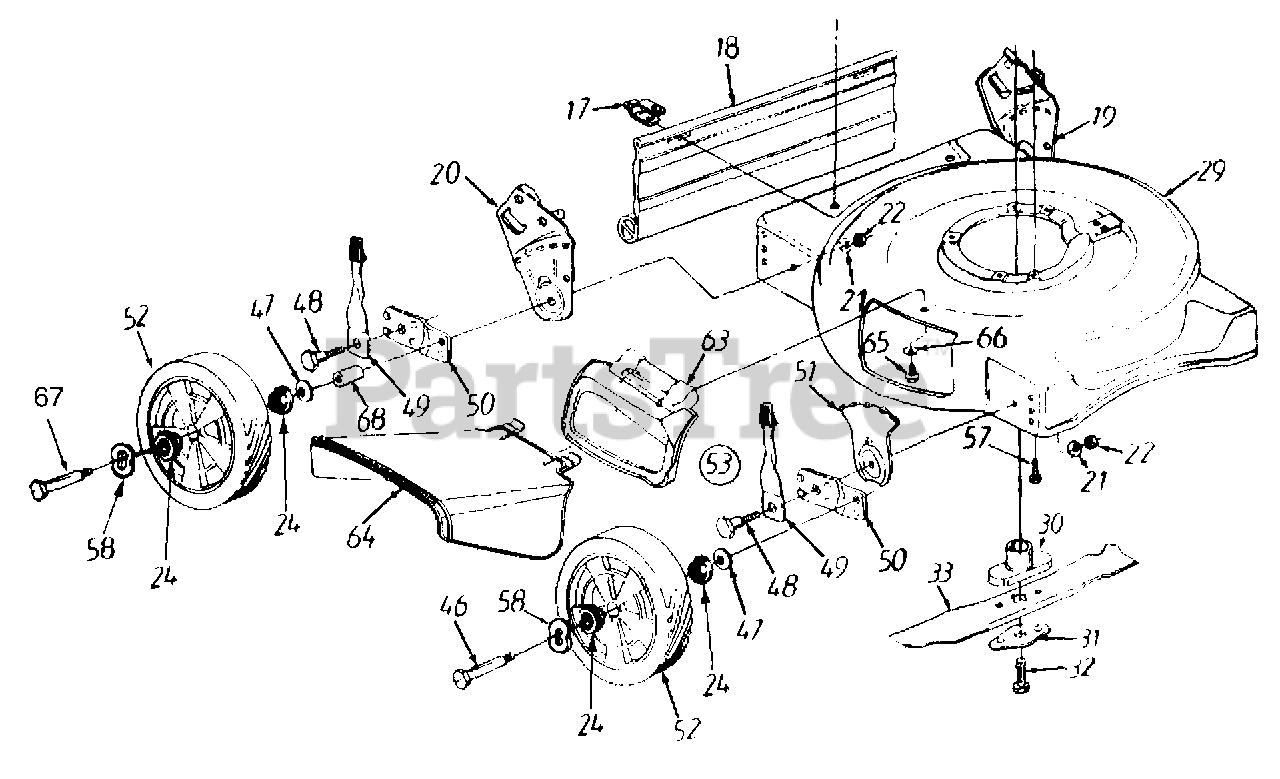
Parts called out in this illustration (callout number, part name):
17	Hinge Clip
18	Rear Flap
19	Handle Bracket Ass'y. LH
20	Handle Bracket Ass'y RH
21	Bell Washer .39" ID x 1.38"
22	Hex Nut 3/8-16 Thd.
24	Bearing
31	Blade Bell Support
32	Hex Bolt 7/16-20 x 1.5"
33	18" Mulch Blade
46	Axle Bolt
47	Bell Washer .400" ID x .88"
48	Shoulder Bolt
49	Spring Lever Ass'y w/Knob
51	Height Adj. Plate
52	Wheel Assembly
53	Height Adj. Ass'y. Comp. R.F. & L.R.
57	Hex Lock Screw 3/8-16 x 1.0"
58	Wave Washer
63	Mulch Plug Assembly
64	Chute Deflector
65	Bell Washer
66	Hex Washerhead Screw 1/4-20 x.5"
67	Shoulder Screw
68	Spacer
